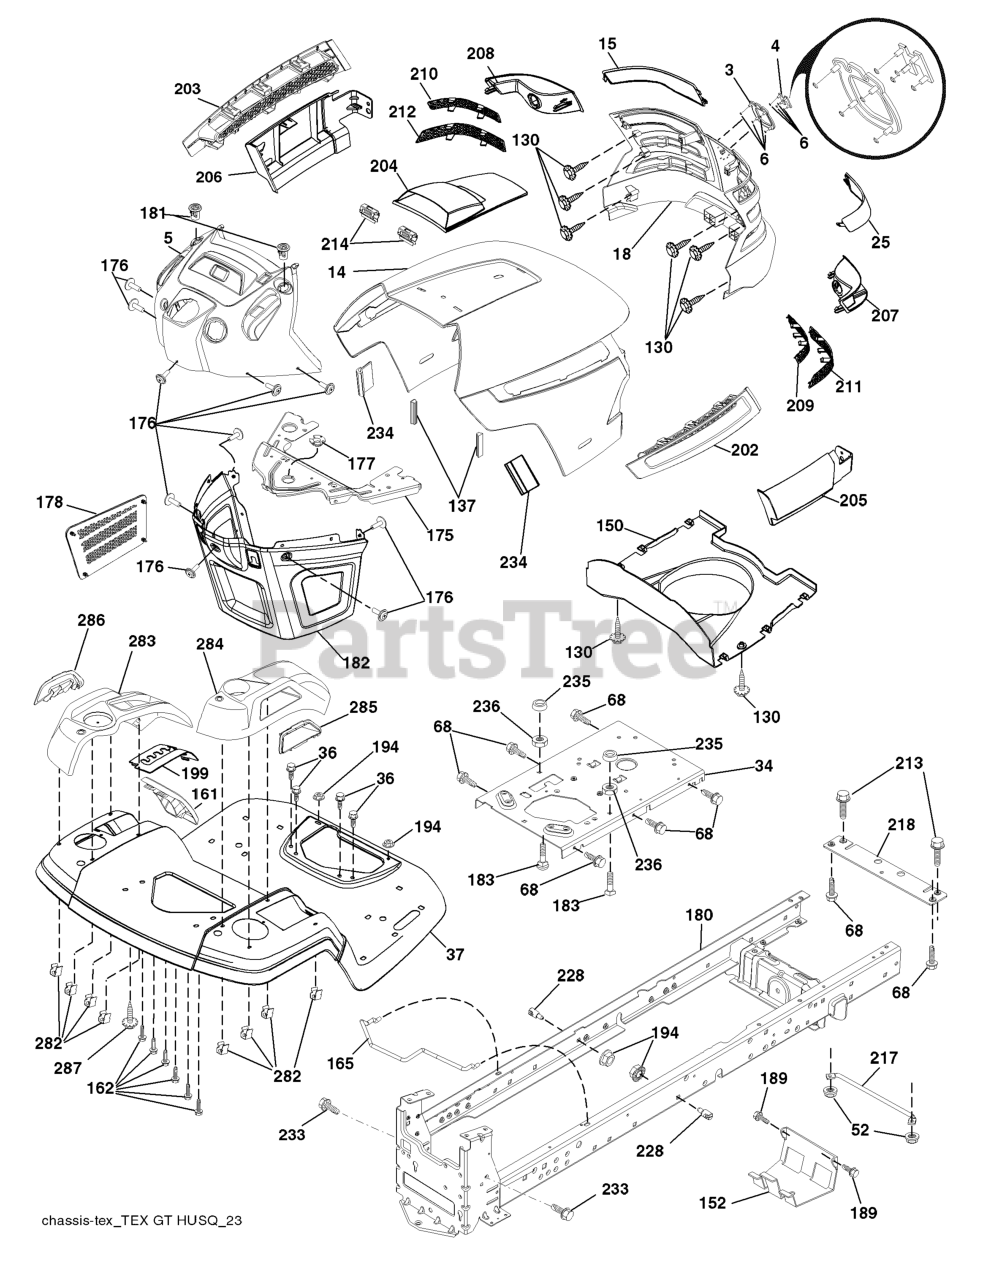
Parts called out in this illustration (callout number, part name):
3	TRIM.HUSQ.TG/CRD.SERVICE
4	RP LOGO
5	DASH.ASM.HUSQ.GT.E.RECT.W/CK
6	NUT PUSH M
14	HOOD
15	LENS.LH.TEX.GT.HUSQ.CL
18	GRILL.ASM.HUSQ.TG/CRD.W/TRIM
25	LENS.RH.TEX.GT.HUSQ.CL
34	PLATE.ENGINE.WELDED.CHASSIS
36	SCREW 5/16"
37	RP FENDER.TLT.FS.W/CPH.422
52	LOCKNUT
68	Screw Thdrol 5/16-18 x 1/2
130	SCREW.#10 X 0.750.BOS
137	BUMPER DASH
150	AIR.DUCT.HOOD.TEX.GT.HUSQ
152	SHIELD.BROWNING.W/TEX
161	WINDOW FUEL
162	SCREW.HI-LO.CONSOLE
165	SUPPORT.TANK.REAR.W/TEX
175	PLATE.CROSSMEMBER.HUSQ
176	SCREW.#10-24X5/8.RN.QU
177	BUSHING, STEERING
178	CARGO.ASM.NET.TXGT.W/C
180	CHASSIS
181	BUSHING.MNT.FEND.CRGO.
182	DASH.LOWER.COMMON.12V.ADAPTOR
183	BOLT.5/16-18X1-1/4 FULL.THREAD
189	SCREW
194	NUT LOCK HEX FLANGE 5/16-18
199	PLATE.DECK.LIFT.HUSQ.LT
202	VENT.SIDE.HOOD.HUSQ.RH.GREY
203	VENT.SIDE.HOOD.HUSQ.LH.GRAY
204	HOOD VENT
205	SKIRT.HOOD.SIDE.HUSQ.RH.GREY
206	SKIRT.HOOD.SIDE.HUSQ.LH.GREY
207	BEZEL.RH.TEX.GT.HUSQ
208	BEZEL.LH.TEX.GT.HUSQ
209	INSERT.HEX.GRILL.HUSQ.GREY
210	INSERT.HEX.GRILL.HUSQ.
211	INSERT.HEX.GRILL.HUSQ.
212	INSERT.HEX.GRILL.HUSQ.
213	BOLT
214	CLIP.RETAINER.TINNER.
217	ROD.PIVOT.HOOD
218	X-PIECE.HOOD.STOP.NON/
228	STUD.FASTNER.W/ANTI-ROTATE
233	BOLT.SHOULDER
234	BUMPER.HOOD.TEX.HUSQVARNA
235	SPACER FENDER
236	NUT.CENTERLOCK.5/16-
282	CLIP.RETAINER.CONSOLE.LT.HUSQ
283	CONSOLE.DECK.LFT.R.SDFL.HUSQLT
284	CONSOLE.CNTRL.
285	CONSOLE INSERT RH
286	CONSOLE.INSRT.LH.HUSQ.LT.BLACK
287	SCREW 1/4X20
